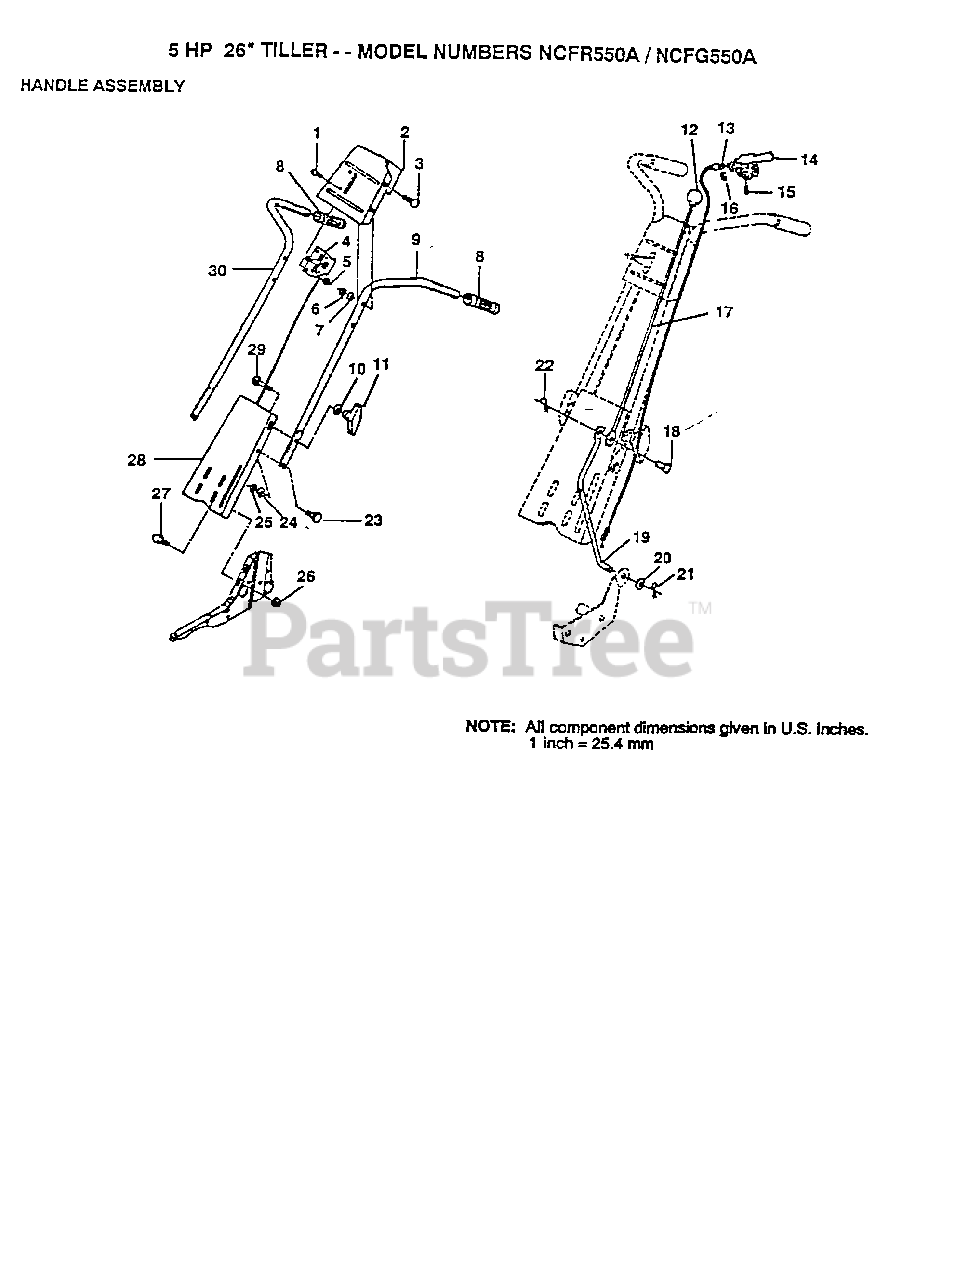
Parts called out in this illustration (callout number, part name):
1	SCREW
2	BRKT HDLE TI
3	BOLT
7	WASHER
10	WASHER
13	CABLE CLUTCH T
14	CONTROL LEVER TI
15	SCREW
16	E-RING
17	ROD REVERSE TI
18	RIVET.RD.HD.DRILL
19	REVERSE ROD TI
20	WASHER
21	COTTER PIN
24	LOCKWASHER
25	NUT.HEX.5/16-18
26	NUT
27	BOLT
29	BOLT
